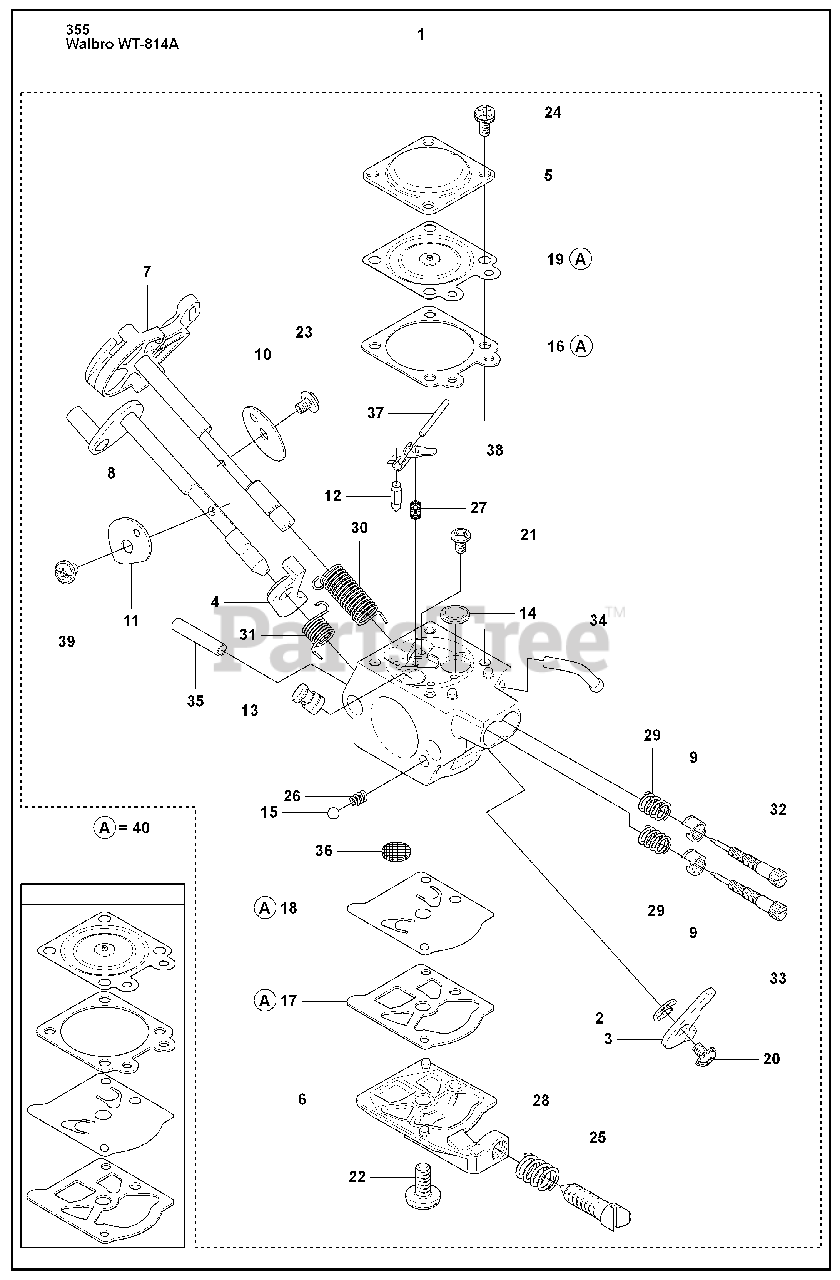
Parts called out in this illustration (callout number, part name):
2	E CLIP
5	THROTTLE SHAFT (W30-832)
9	LIMITER CAP
12	INLET NEEDLE
14	PLUG
18	DIAPHRAGM, FUEL PUMP
19	METERING DIAPHRAGM
23	SCREW
24	RP SCREW W/ WASHER
28	SPRING
36	FUEL INLET SCREEN
37	FULCRUM PIN
